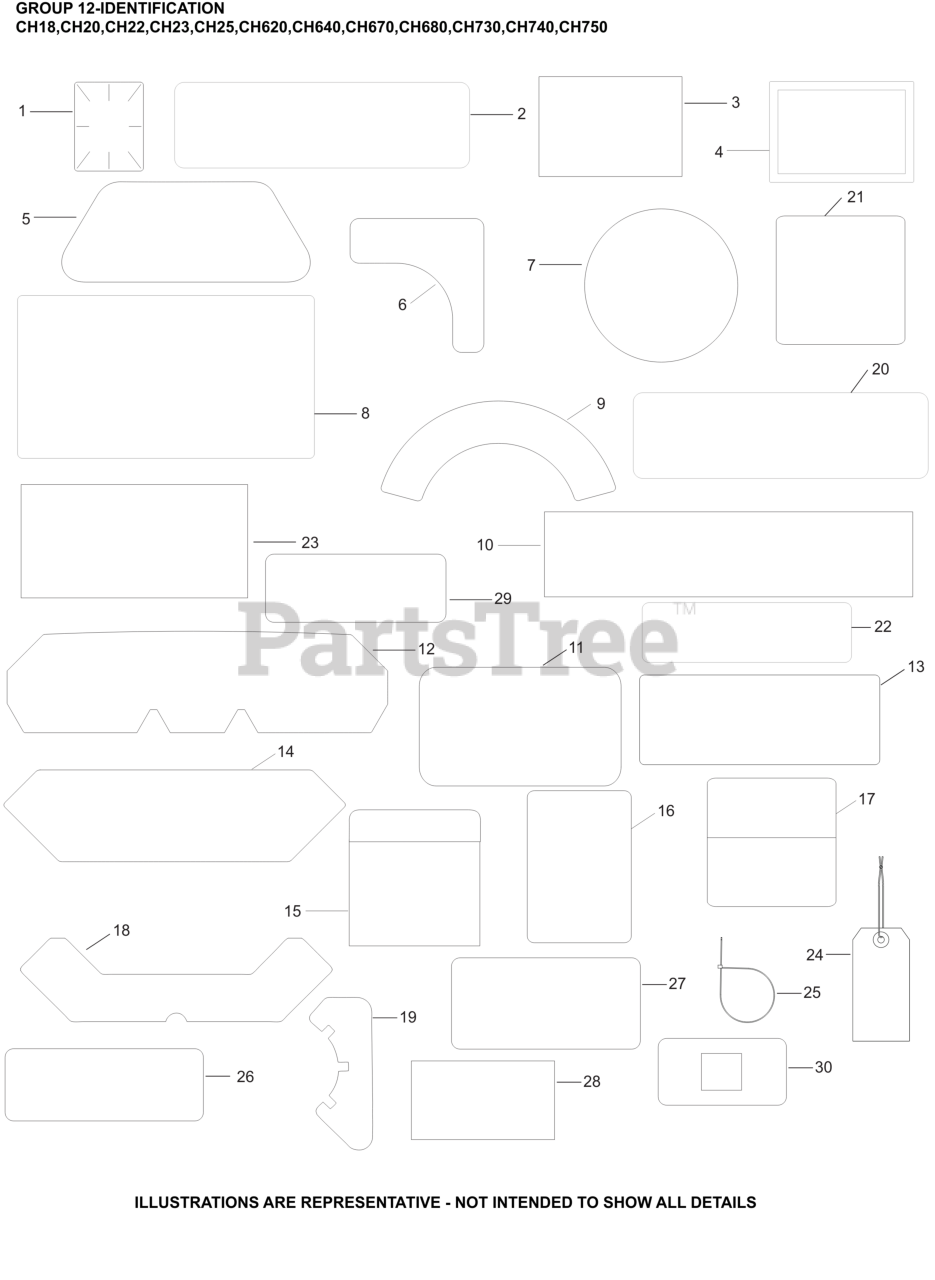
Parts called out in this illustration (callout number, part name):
1	LABEL, CLEAR LAMINATION
7	LABEL, GRASS SCREEN
10	DECAL, STOPPING INSTRUCTION
20	DECAL LPAC, 25 HP/725cc/CV-CH740
24	TAG, HANG (OIL SENTRY)
28	DECAL, USA
